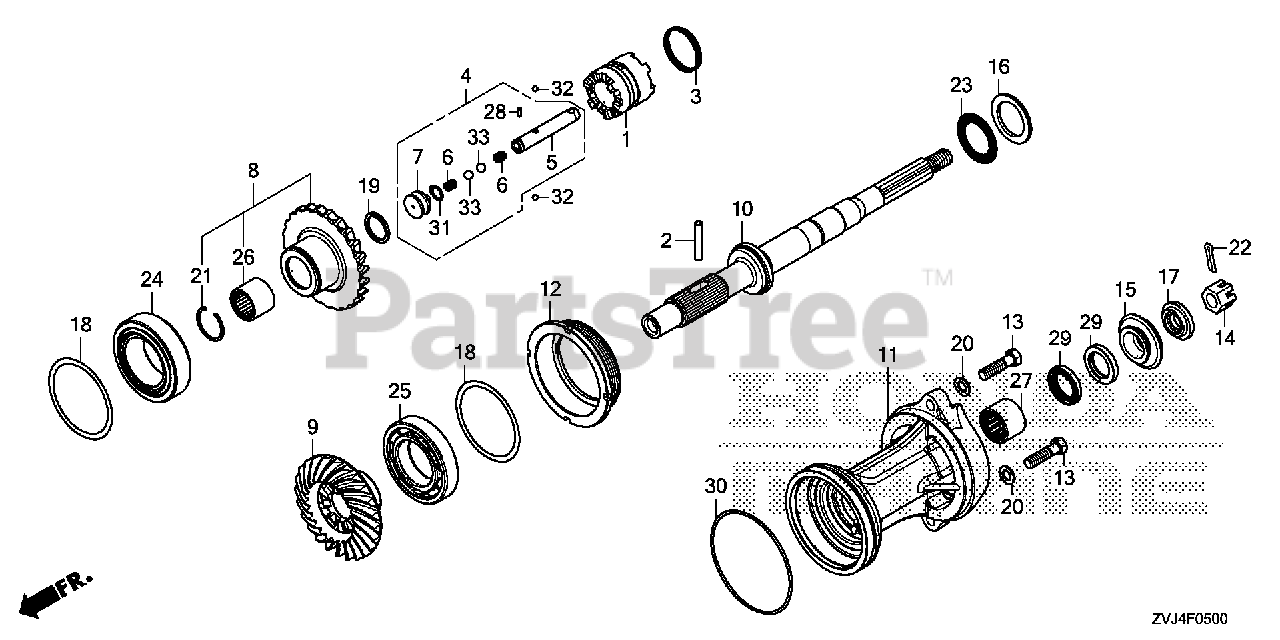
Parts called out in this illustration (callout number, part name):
1	SHIFTER, CLUTCH
2	PIN, SHIFTER (8X50)
3	RING, CROSS PIN
4	SLIDER, SHIFT
5	SLIDER, SHIFT
6	SPRING, SHIFT
7	PLATE, SHIFT
8	GEAR, BEVEL (24T) (FORWARD)
9	GEAR, BEVEL (24T) (REVERSE)
10	SHAFT, PROPELLER
11	HOLDER, PROPELLER SHAFT *NH565* (GRAND PRIX WHITE)
11	HOLDER, PROPELLER SHAFT *NHB14M* (AQUA MARINE SILVER METALLIC)
12	HOLDER, BEARING
13	BOLT, HEX. (12X45)
14	NUT, CASTLE (18MM)
15	WASHER, PROPELLER THRUST
16	WASHER, THRUST BEARING
17	WASHER, PROPELLER
18	SHIM A, BEVEL (0.10)
18	SHIM B, BEVEL (0.15)
18	SHIM C, BEVEL (0.30)
18	SHIM D, BEVEL (0.50)
19	SHIM A, THRUST (2.75)
19	SHIM B, THRUST (2.80)
19	SHIM C, THRUST (2.85)
19	SHIM D, THRUST (2.90)
19	SHIM E, THRUST (2.95)
19	SHIM F, THRUST (3.00)
19	SHIM G, THRUST (3.05)
19	SHIM H, THRUST (3.10)
19	SHIM I, THRUST (2.70)
19	SHIM J, THRUST (2.65)
19	SHIM K, THRUST (2.60)
19	SHIM L, THRUST (2.55)
19	SHIM M, THRUST (2.50)
20	WASHER, PLAIN (12MM)
21	RING, SETTING (39)
22	PIN, SPLIT (4.0)
23	BEARING, THRUST (F)
24	BEARING, TAPER ROLLER (60X100X30)
25	BEARING, RADIAL BALL (55X100X21)
26	BEARING, NEEDLE (28X39X30)
27	BEARING, NEEDLE (32X42X30)
28	ROLLER (3X13.8)
29	SEAL, WATER (30X45X7)
30	O-RING (121X3.1)
31	CIRCLIP, OUTER (15MM)
32	BALL, STEEL (#7) (7/32)
33	BALL, STEEL (#12) (3/8)
